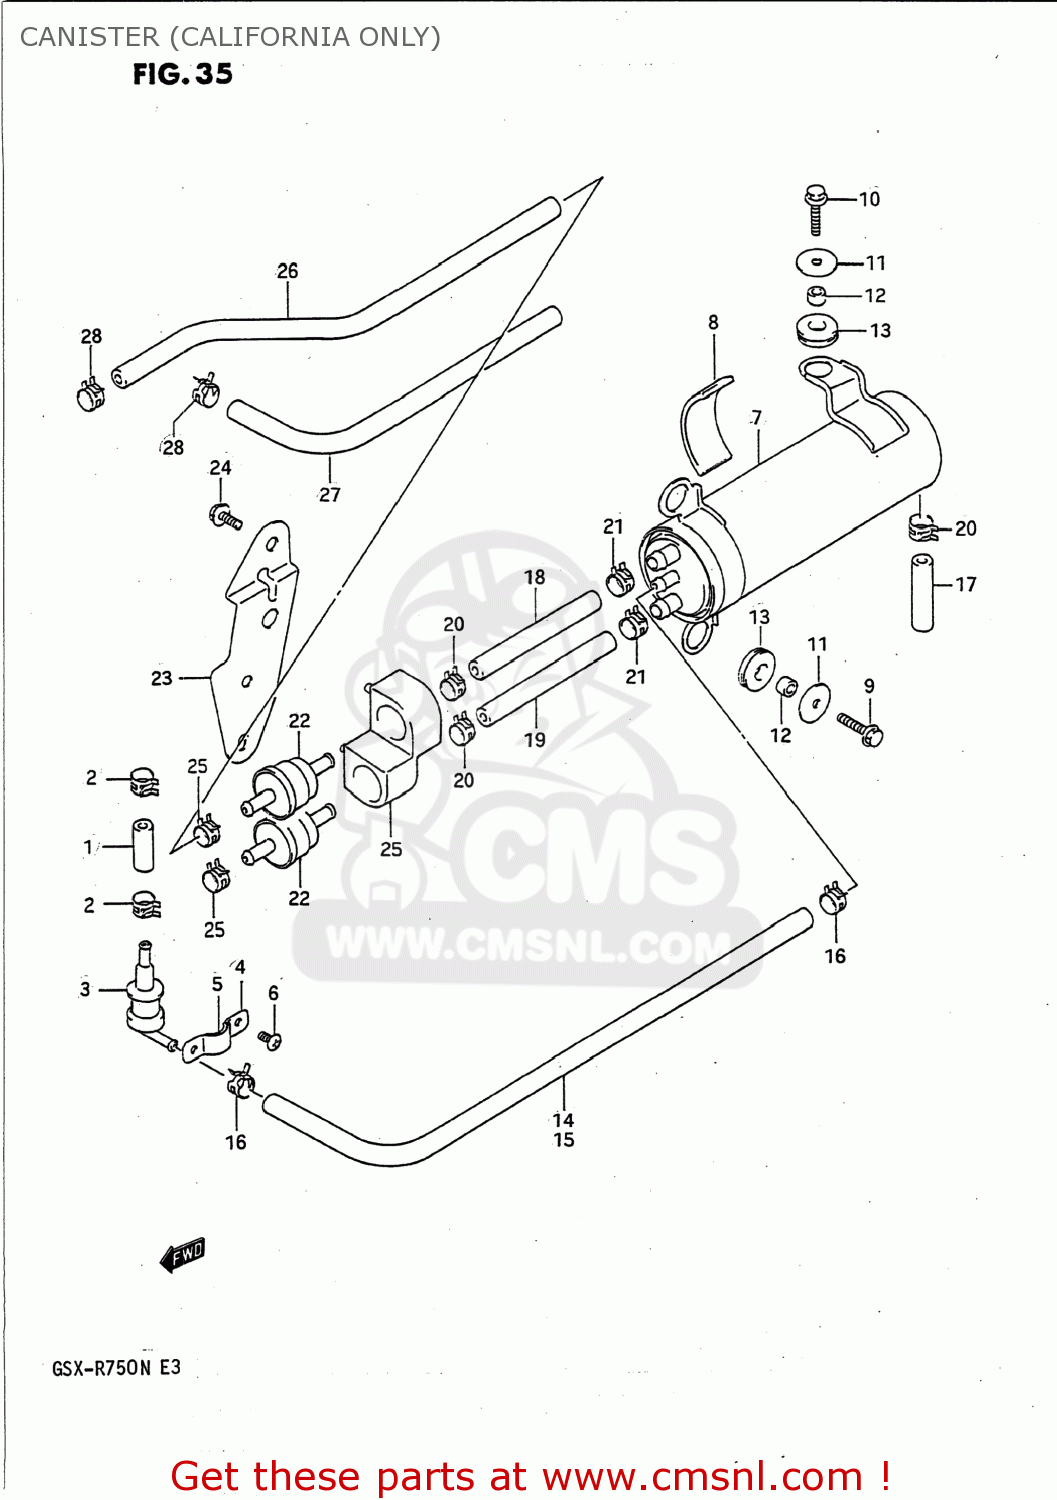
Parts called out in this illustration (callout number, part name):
1	HOSE
2	(CA) CLIP
3	VALVE,FUEL TANK BREATHER
4	PLATE,FUEL TANK BREATHER NO.2
5	CUSHION
6	SCREW
7	(CA) CANISTER COMP,CHARCOAL
8	(CA) CUSHION,CANISTER
9	BOLT
10	BOLT
11	WASHER (6.5X24X1.6)
12	SPACER(6.5X10.5X6.5)
13	CUSHION
14	HOSE
15	PROTECTOR(14.5X15.5X600)
16	(CA) CLIP
17	HOSE (7X12X300)
18	HOSE
19	HOSE
20	(CA) CLIP
21	CLAMP
22	VALVE,CANISTER PURGE
23	BRACKET,CANISTER
24	BOLT
25	(CA) CUSHION,CANISTER P VA
26	HOSE (5.4X11.4X600)
27	HOSE (5.4X11.4X600)
28	(CA) CLIP
